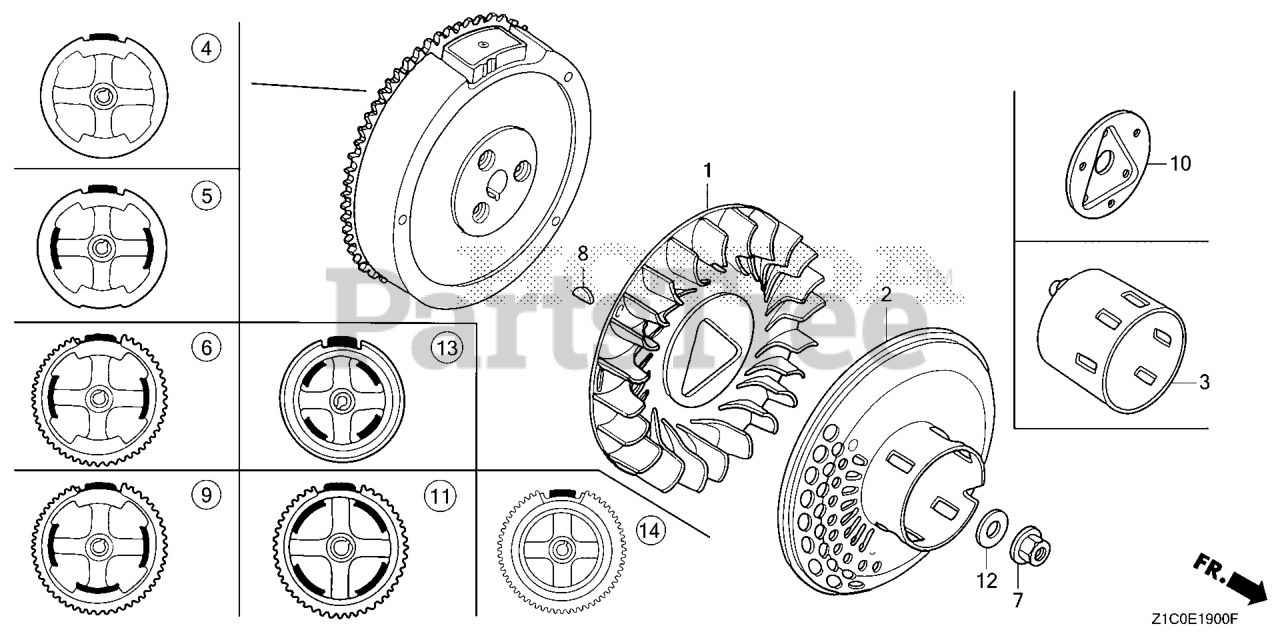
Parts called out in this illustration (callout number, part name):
1	FAN, COOLING
2	PULLEY, STARTER (SCREEN GRID)
7	NUT, SPECIAL (16MM) (1)
8	KEY, SPECIAL WOODRUFF (25X18)
11	FLYWHEEL (SEL-4POLE)
